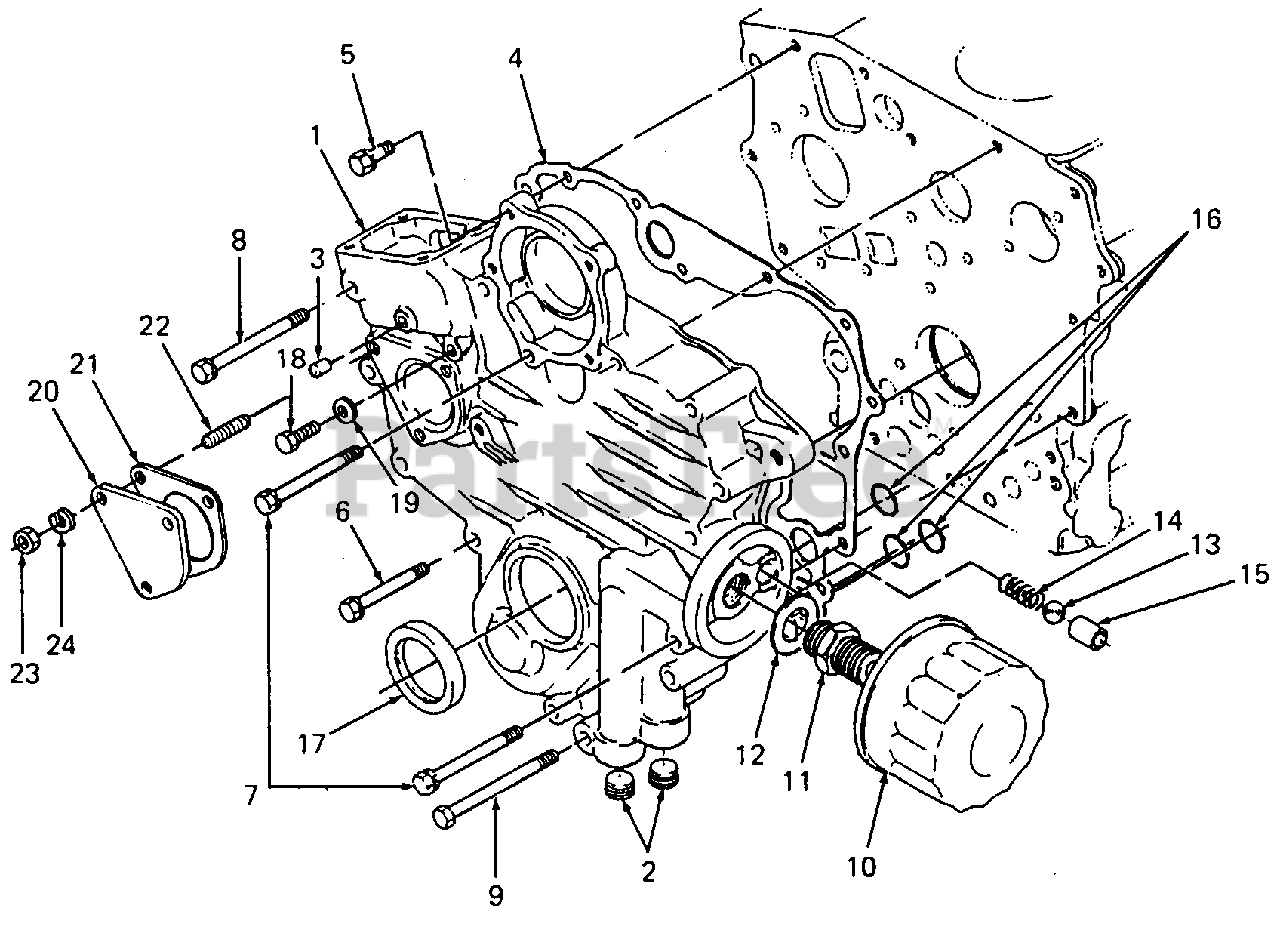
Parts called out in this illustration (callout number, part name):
1	Gear Case Assy
4	Gasket, Gear Case
10	Element, Filter
12	Washer, Plain
24	Washer, Spring
